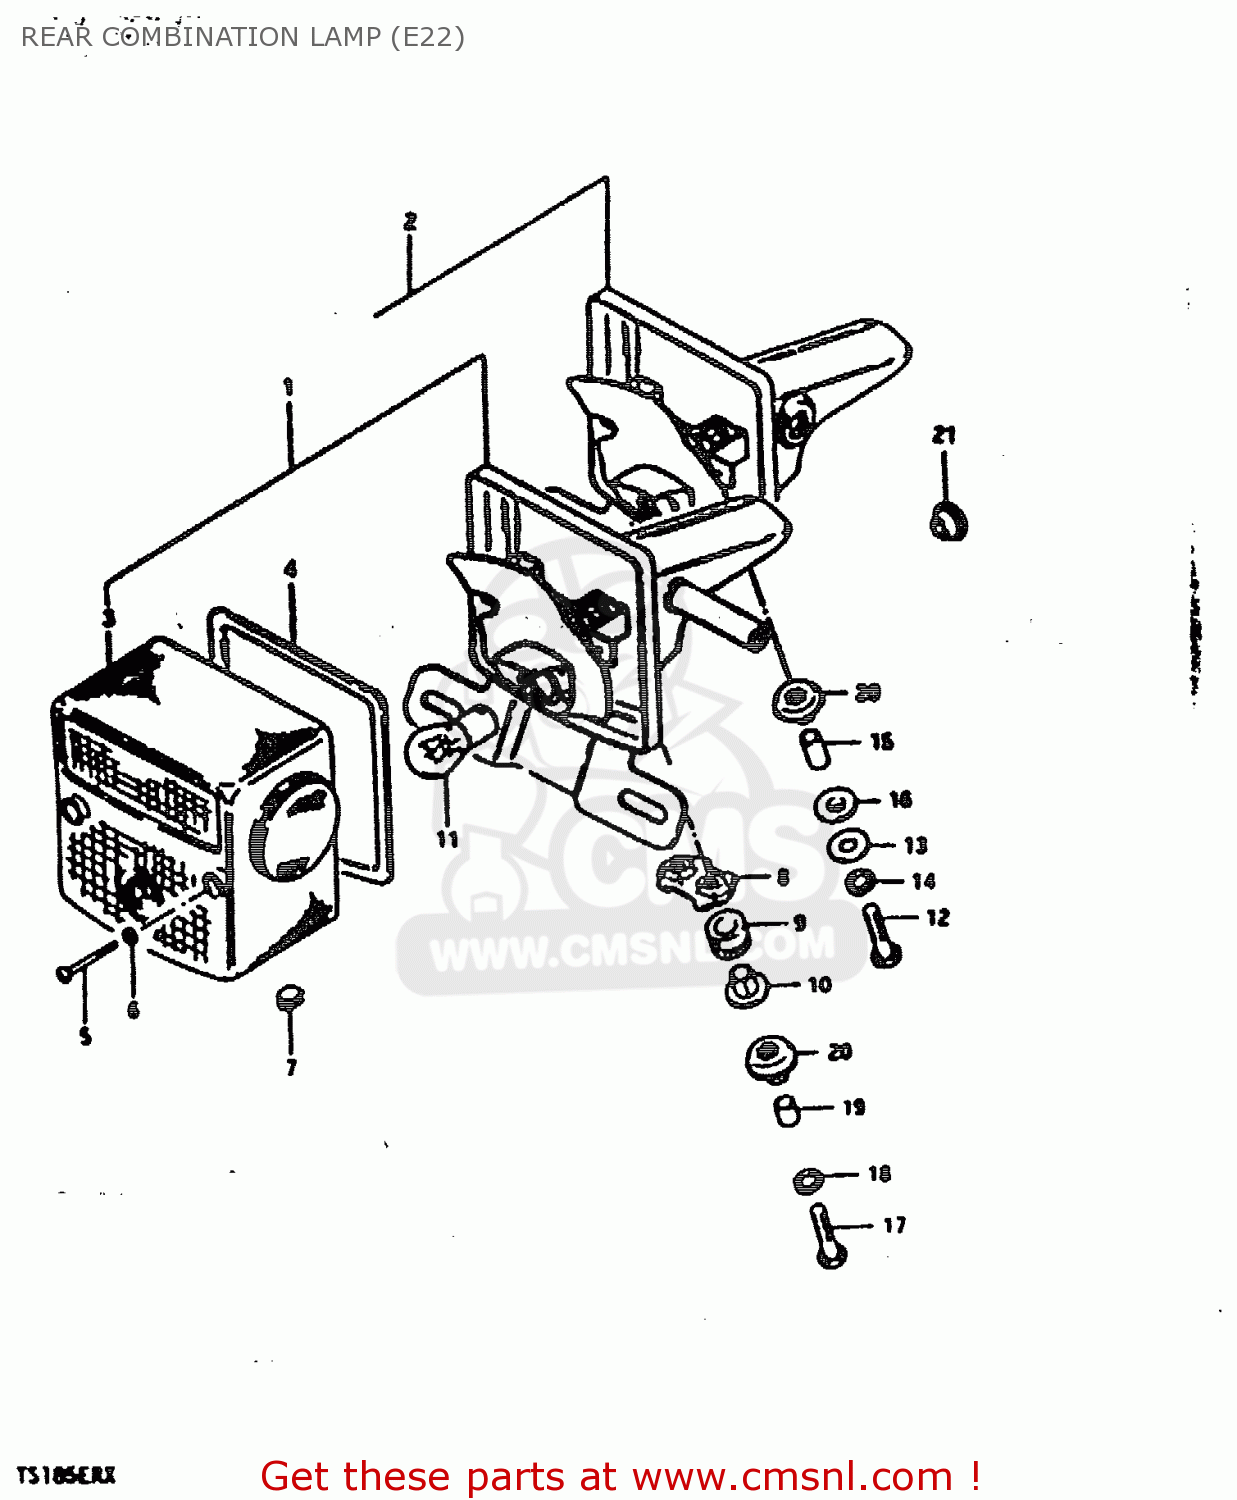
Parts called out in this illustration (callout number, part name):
1	LAMP ASSY, REAR COMBINATION
2	LAMP ASSY, TAIL
3	LENS
4	GASKET (NAS)
5	SCREW (4X55)
6	GASKET (NAS)
7	GROMMET,REAR COMBINATION LAMP
8	PLATE
9	CUSHION
10	SPACER
11	BULB (6V,21/5W)
12	BOLT
13	WASHER (6.5X20X1.2)
14	LOCK WASHER
15	SPACER
16	CUSHION
17	BOLT 6X40
18	LOCK WASHER
19	SPACER (6.8X10X11.5)
20	CUSHION
21	GROMMET
